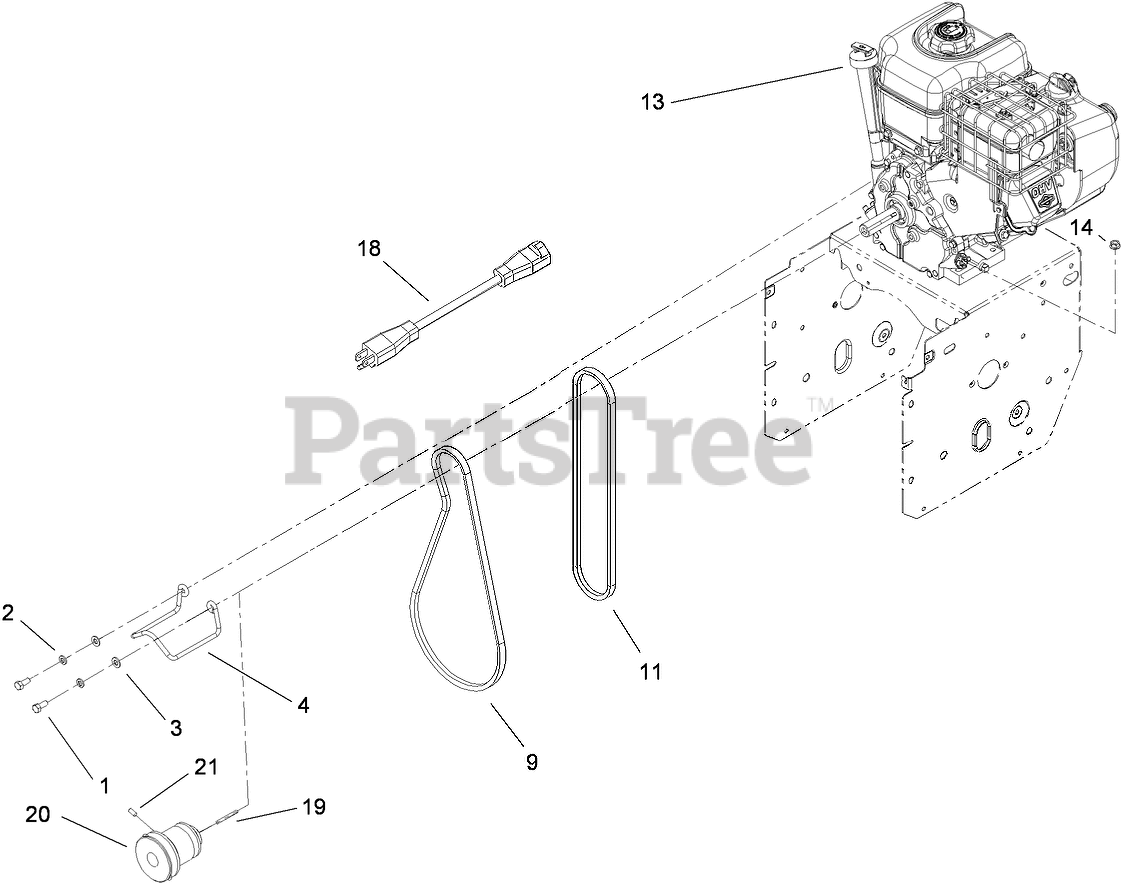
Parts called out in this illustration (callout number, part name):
1	SCREW-HH
2	WASHER-LOCK
3	WASHER-PLAIN
4	GUIDE-BELT
9	BELT-V
11	V BELT-TRACTION
14	NUT-HF
18	CORD-EXTENSION
19	KEY-SQUARE
20	PULLEY-ENGINE
21	SCREW-SET, HSH
